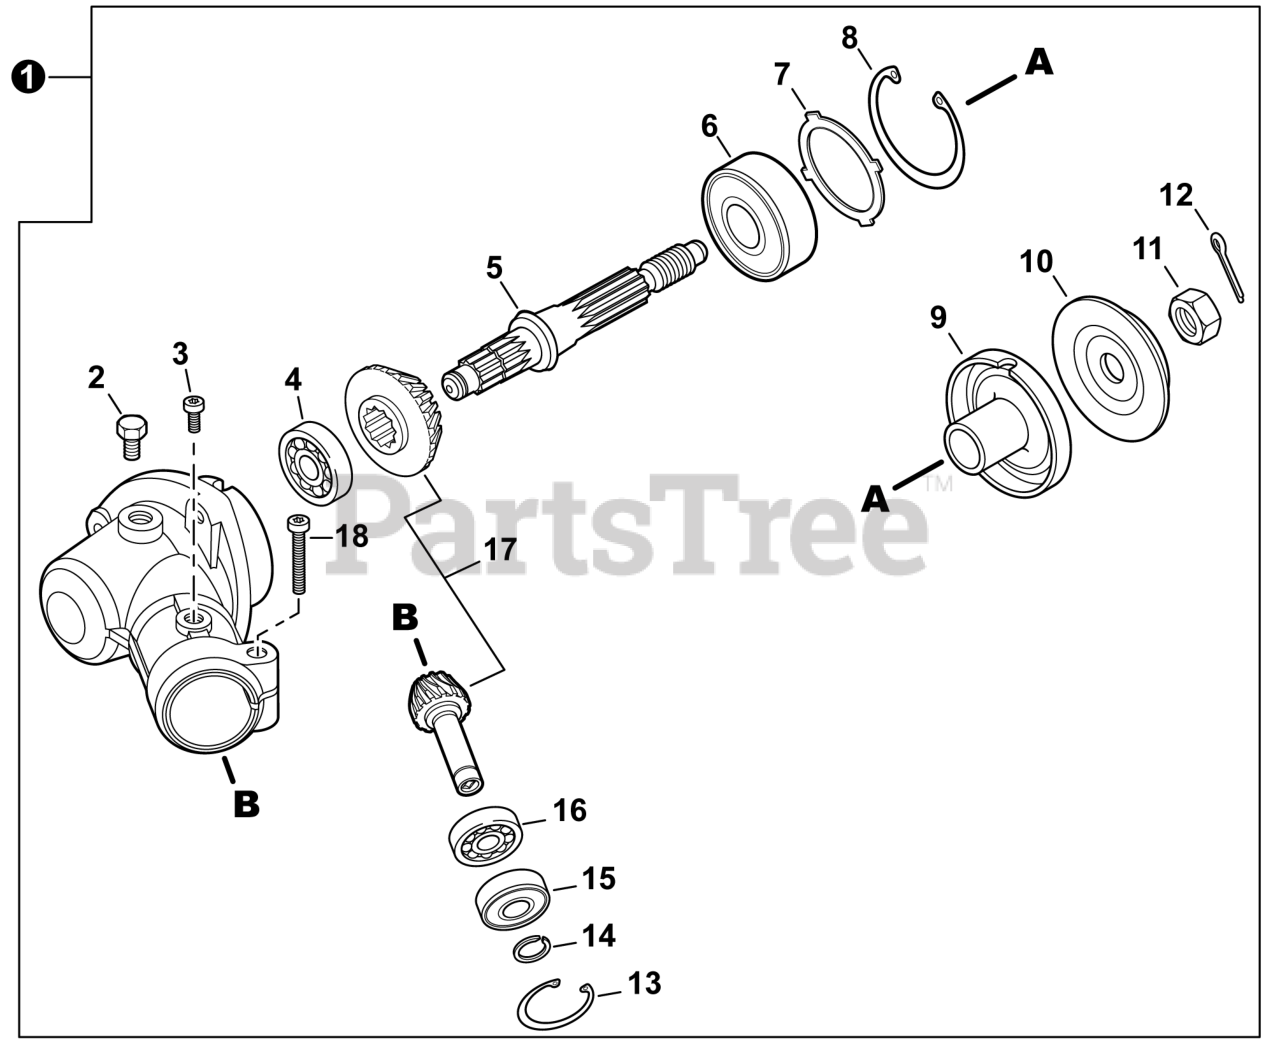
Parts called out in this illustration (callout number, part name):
1	GEAR CASE ASSY
2	BOLT M8x8
3	BOLT, TORX 5x10
4	BEARING, BALL 629
5	SHAFT, GEAR
6	BEARING, BALL 6201
8	RING, SNAP 32
9	PLATE, ADAPTOR - UPPER
10	PLATE, ADAPTOR - LOWER
11	NUT 10x1.25 LH
12	PIN, COTTER 2x22
13	RING, SNAP 25
14	RING, SNAP 9
15	BEARING, BALL 609ZA
16	BEARING, BALL 609A
17	GEAR SET
18	BOLT, TORX 5x25
